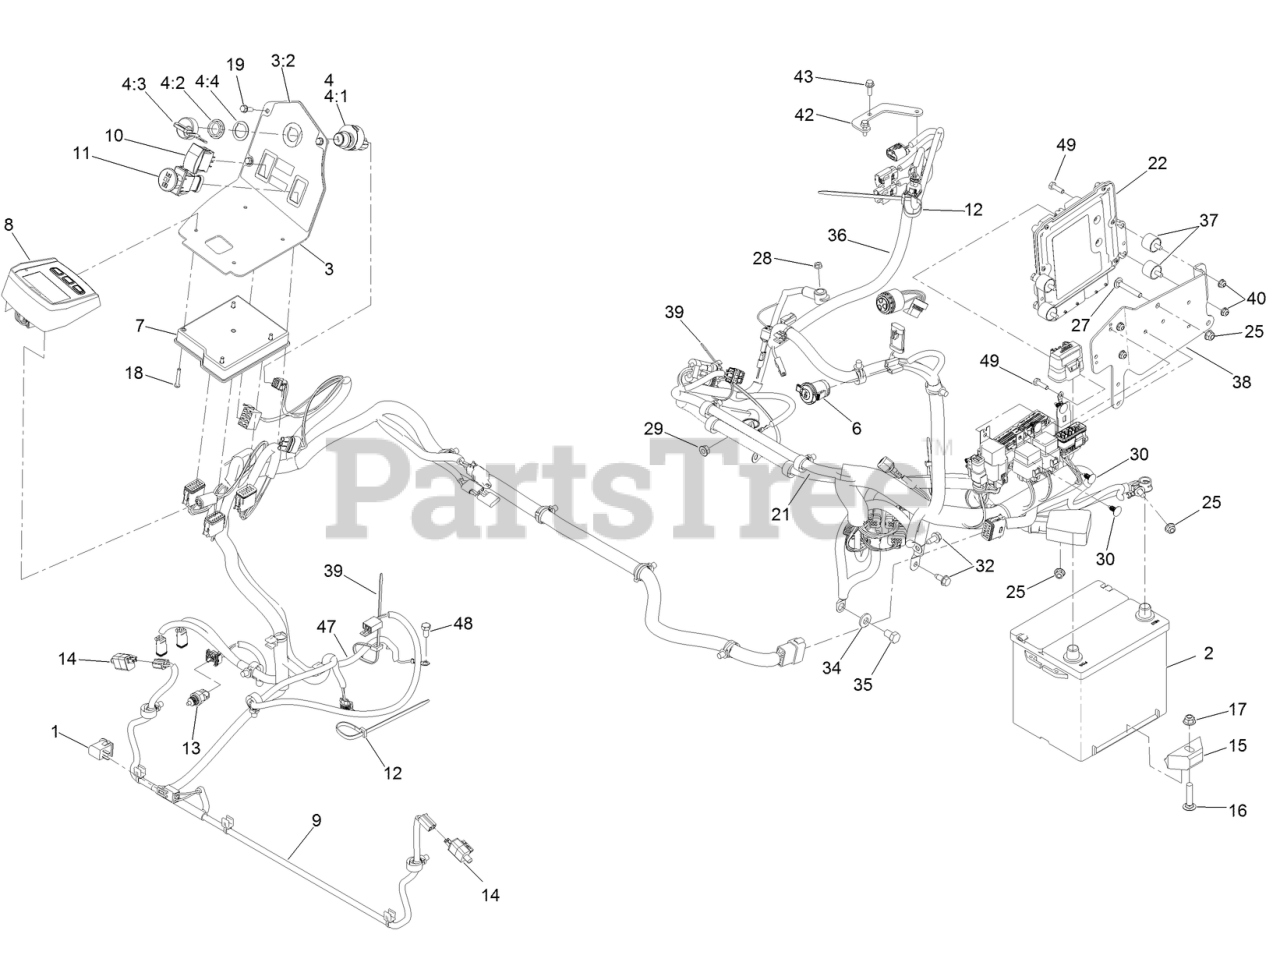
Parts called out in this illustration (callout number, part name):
1	SWITCH-BAIL
2	BATTERY-DRY
3	CONSOLE ASM
3:2	DECAL-CONTROL PANEL
4	IGNITION SWITCH ASM
4:1	HUB and BEARING ASM
4:2	NUT-MOUNTING
4:3	IGNITION KEY SET
4:4	WASHER-BACKUP
6	PORT-POWER, 12V
7	MODULE-MCU
8	MODULE-HORIZON
9	HARNESS-WIRE
10	SWITCH
11	SWITCH-PTO, SEALED
12	TIE-PLASTIC
13	SENSOR-TEMPERATURE
14	SWITCH
15	RETAINER-BATTERY
16	SCREW-CARR
17	NUT-HF, NI
18	SCREW-PPH
19	SCREW-HWH
21	CABLE-BATTERY
22	E C U ASM
25	NUT-HF, NI
27	BOLT-CARR
28	NUT-HF
29	NUT-HF
30	PLUG-PLASTIC
32	SCREW-HWHTF
34	WASHER-BELLEVILLE
35	SCREW-HH
36	HARNESS-WIRE
37	MOUNT-CYLINDRICAL
38	MOUNT-CONTROL UNIT, ENGINE
39	TIE-CABLE
40	NUT-HF
42	BRACKET-WIRING, ENGINE
43	SCREW-HHF
47	HARNESS-WIRE, JUMPER
48	BOLT
49	SCREW-HH
